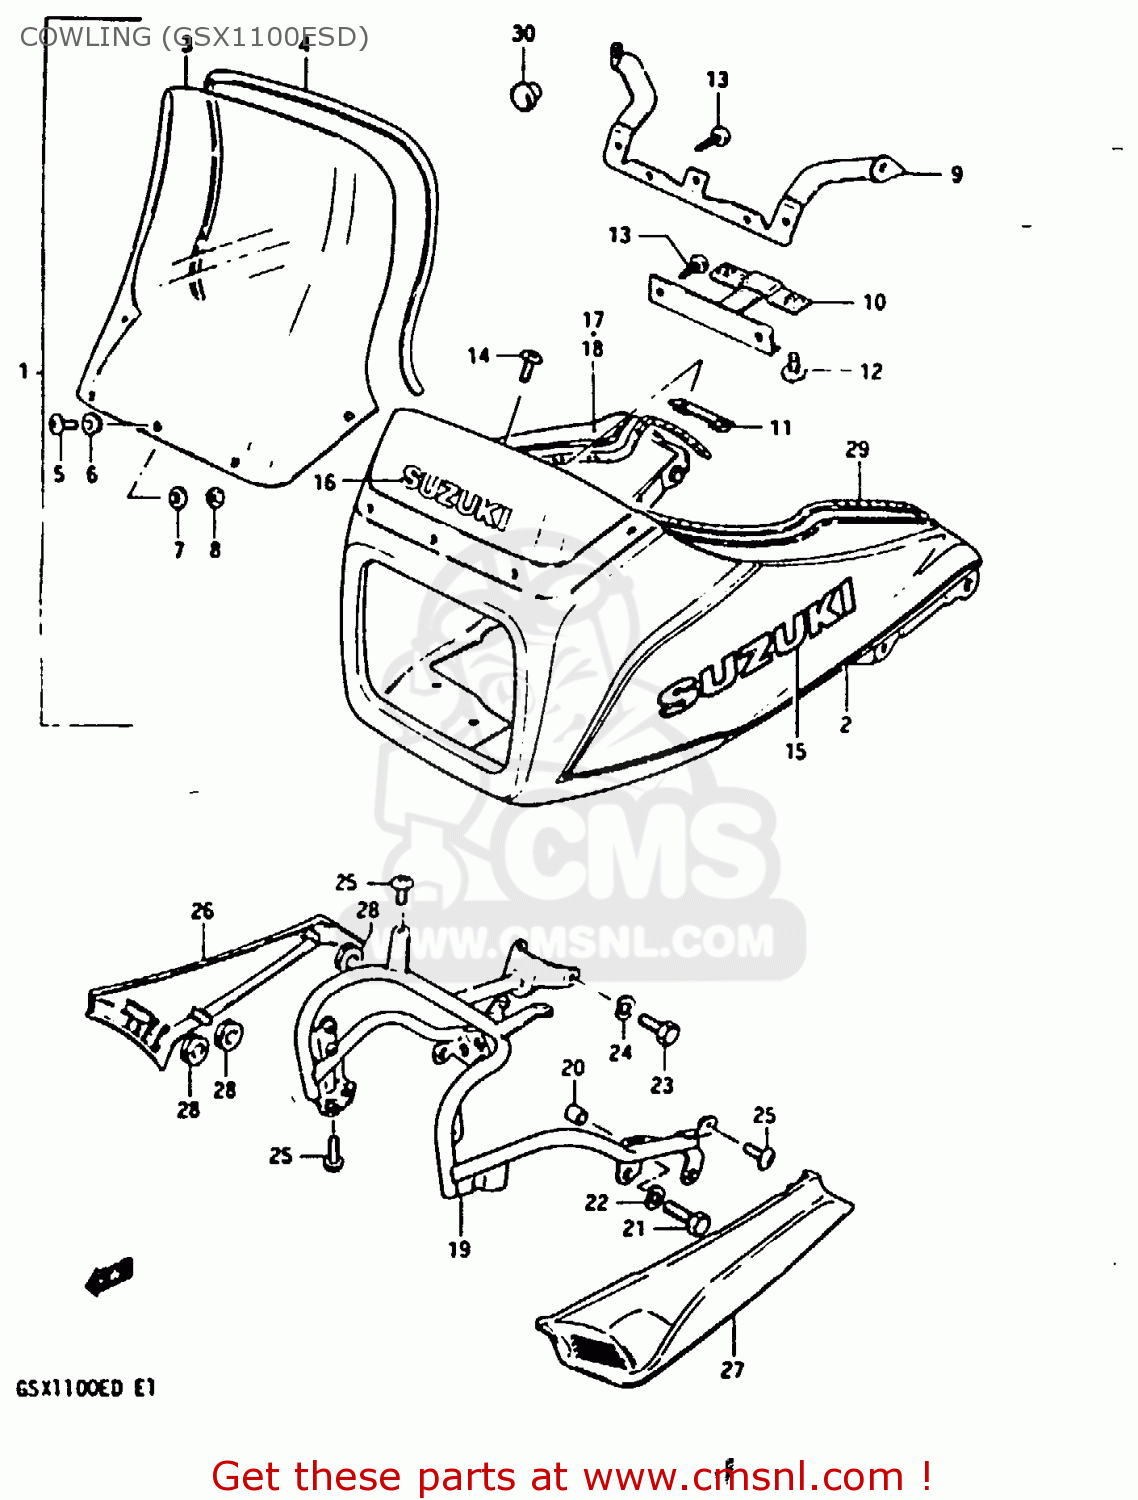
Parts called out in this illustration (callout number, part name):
1	COWLING ASSY
2	TAPE SET,COWLING
3	WINDOW
4	MOLDING
5	SCREW(5X20)
6	CUSHION
7	WASHER
8	NUT
9	BRACE,COWLING,UPPER
10	BRACE,COWLING,LOWER
11	BRACKET
12	SCREW
13	SCREW
14	SCREW RH & LH
15	EMBLEM
16	EMBLEM,HEADLAMP
17	TAPE,RIGHT
18	TAPE,LEFT
19	BRACE,COWLING
20	SPACER,COWLING BRACE
21	BOLT (8X30)
22	LOCK WASHER
23	BOLT
24	LOCK WASHER
25	SCREW 6X12
26	COVER,COWLING,RIGHT
27	COVER,COWLING,LEFT
28	CUSHION
29	MOLDING,FUEL TANK
30	PLUG(OD:12)
